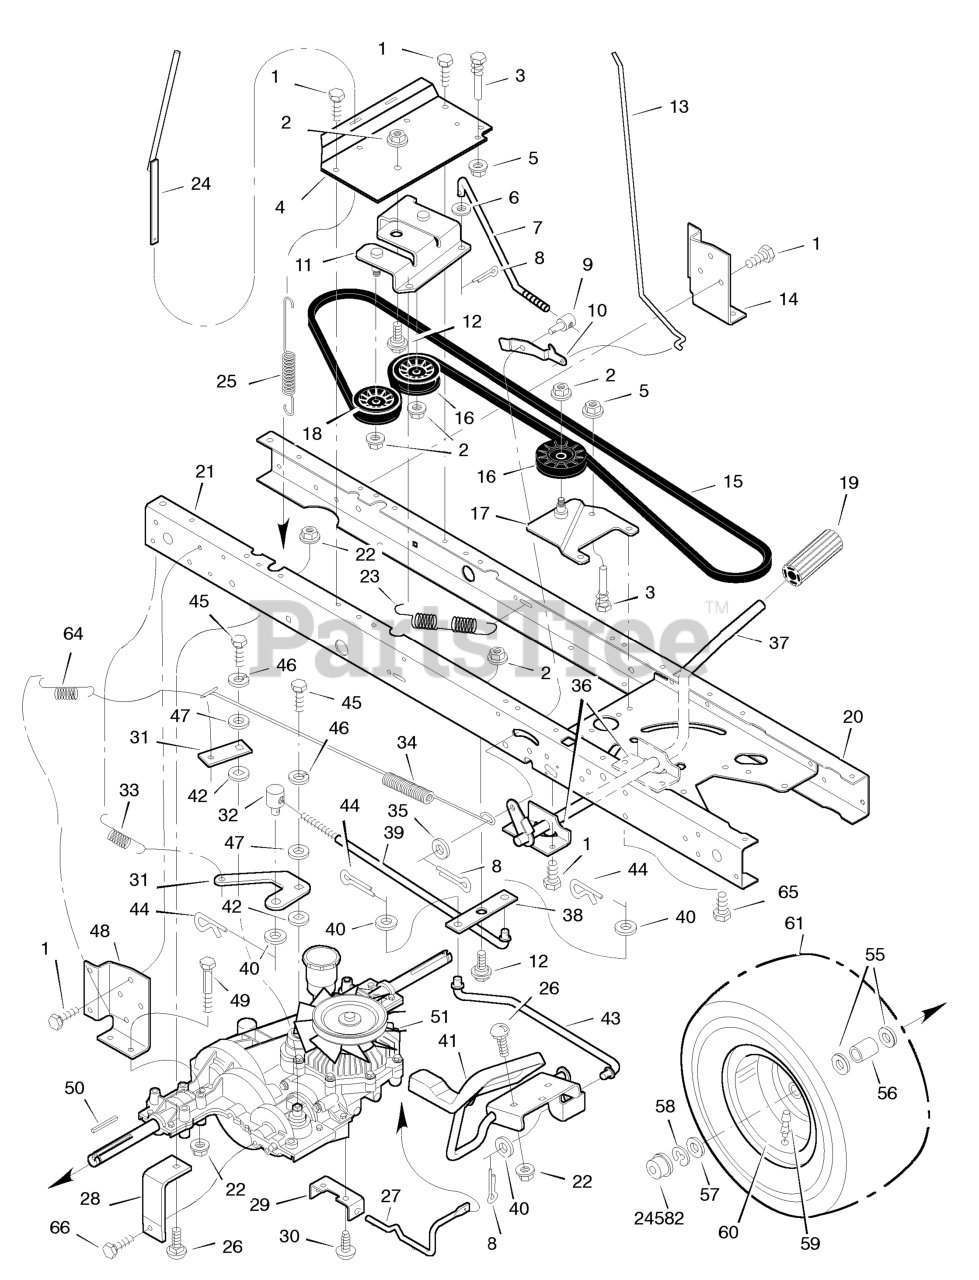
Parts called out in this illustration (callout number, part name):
2	Nut, Flange
3	Guide, Belt
4	Bracket, Idler
5	Locknut
6	Washer
7	Rod, Clutch
8	Pin, Cotter
9	Adjuster
10	Latch, Parking Brake
11	Bracket Assembly, Idler
12	Bolt, Shoulder
13	Rod, Parking Brake
14	Bracket, Transaxle
16	Pulley, Idler
17	Bracket Assembly, Idler
18	Pulley, Idler
19	Pedal
20	Frame, Left
21	Frame, Right
22	Nut, Flange
23	Spring, Extension
24	Lever Assembly, Tow Valve
25	Spring, Extension
26	Bolt, Carriage
27	Rod, Dump Valve
28	Strap, Right Torque
29	Bracket, Dump Valve
31	Arm, Brake
32	NUT, Adjusting, 1/2-13
33	Spring, Extension
34	Spring, Extension
35	Washer
36	Bracket, Pivot
37	Lever, Clutch/Brake
38	Bellcrank
39	Rod, Pedal Link - Rear
41	Pedal, Speed Control
43	Rod, Pedal Link - Front
44	Pin, Hair
46	Lockwasher
48	Bracket, Right Transaxle
49	Bolt
50	Key, Square
51	Transaxle **
58	E- Ring
59	Valve Stem
60	Wheel & Tire Assembly
62	Cap, Hub
63	Control Arm
64	Spring, Extension
